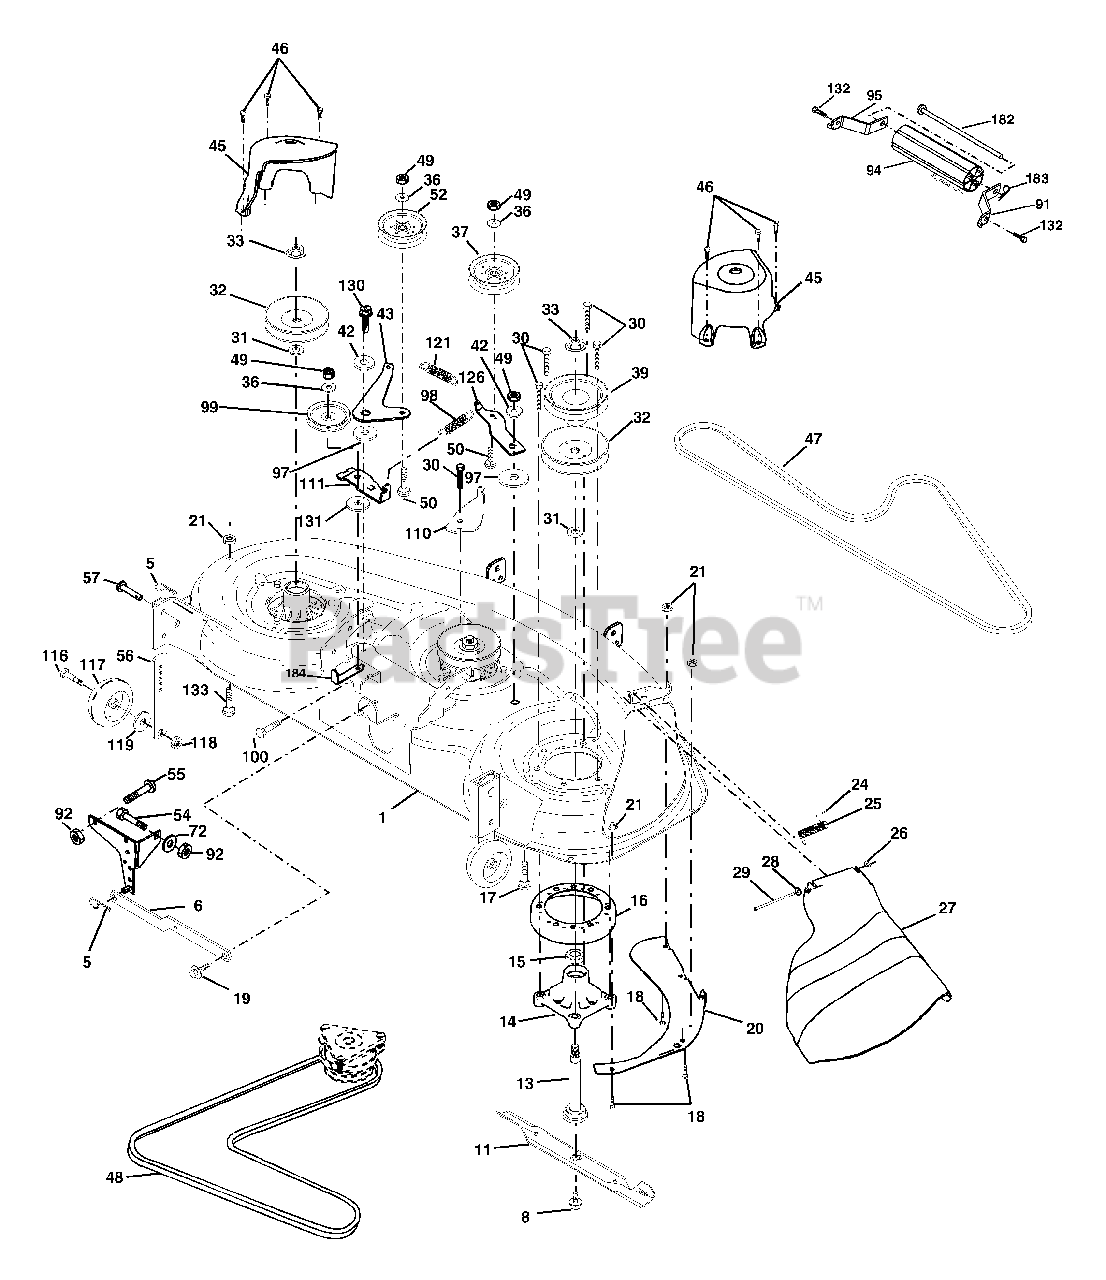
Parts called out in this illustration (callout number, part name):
1	Deck Weldment Mower 48
3	Bracket Asm., Sway Bar
5	Retainer Spring
6	Bar Sway Deck
8	Bolt, 7/16 Asm. Blade
13	Shaft Asm. Mandrel Sealed
14	Housing Mandrel 48"
15	Bearing, Ball, Mandrel
16	Stripper, Mower
17	Bolt Rdhd Sq Neck 3/8-16 x 1.25
18	Bolt, Carriage 5/16-18 x 5/8
19	Bolt, Hex Head, Shoulder 5/16-18
20	Baffle, Vortex Mower
21	Nut, Crownlock 5/16-18 unc
24	Cap, Sleeve
25	Spring, Torsion
27	Shield, Deflector Mower
28	Washer 11/32 x 5/8 x 16 Ga.
29	Rod, Hinge
30	Screw, Thdroll, Washer Head
31	Washer, Spacer Mower Vented
32	Pulley, Mandrel
33	Nut, Flg. Top Lock Cntr. 9/16
36	Washer 13/32 x 13/16 x 16 Ga.
37	Pulley, Idler, Flat
39	Pulley, Idler, Driven
42	Spacer, Retainer
43	Arm, Idler Secondary
45	Cover, Mandrel Deck
46	Screw, Thdroll. 1/4-20 x 5/8
47	V-Belt, Mower, Secondary
48	V-Belt, Mower, Primary
49	Nut, Crownlock 3/8-16 unc
50	Bolt, Carriage 3/8-16 x 1-1/2 Gr. 5
52	Pulley Idler Flat 46 Pri. Drive
54	Bolt Fin Hex 3/8-16 x 1
55	Bolt Rdhd Sqnk 3/8-16 x 1
56	Bar Pnt Adjusting Wheel Gauge
57	Pin Head Rivet
72	Washer 13/32 x 13/16 x 12
91	Bracket, Asm Noseroller, RH 48
92	Nut Lock Hex w/Ins 3/8-16
94	Roller, Nose 48"
95	Bracket, Asm Noseroller LH 48
97	Washer Hardened
98	Spring Primary Drive
99	Pulley Idler "V"
100	Bolt RDHD Sqnk 3/8-16 unc x 2
110	Arm Spring Secondary
111	Arm Spring Fixed Tension
116	Bolt, Shoulder
117	Gauge Wheel
118	Nut, Centerlock 3/8-16 unc
119	Washer 3/8 x 7/8 x 14 Ga.
121	Spring Secondary Drive
126	Arm, Idler, Primary Deck
130	Screw 3/8-16 x 1.0
131	Washer 13/32 x 1 x 6 Ga.
132	Screw 3/8-16 x 3/4
133	Bolt Rdhd Sqnk 5/16-18 unc x 3/4
182	Rod Roller Nose
183	Retainer Spring
184	Keeper Belt Idler
